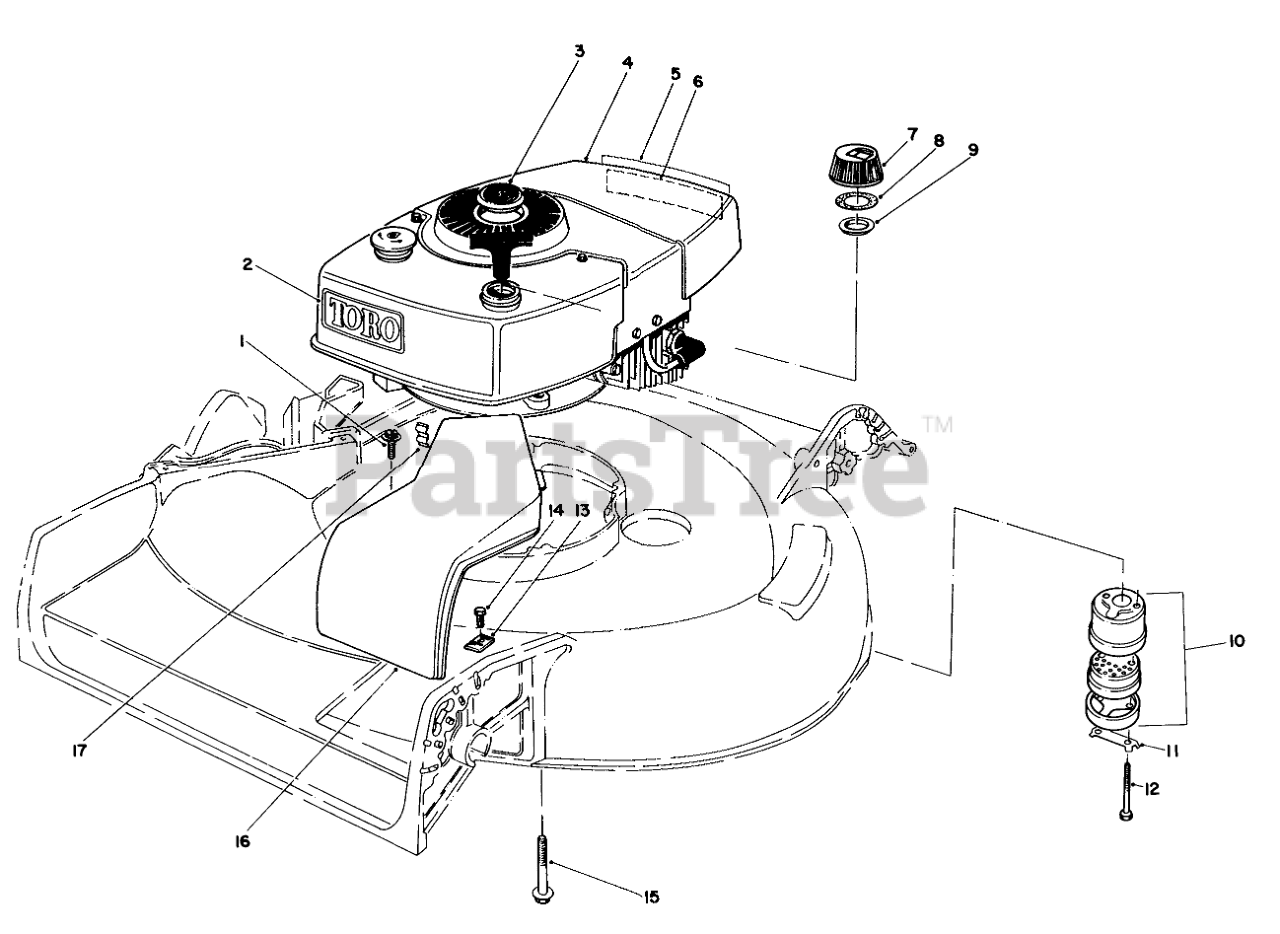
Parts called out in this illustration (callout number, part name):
1	SCREW
2	Decal Tow
3	Plug Button
4	Engine
5	Decal-Primer
6	Decal Maintenance
7	Fuel Cap (Incl. Ref. #8 & 9)
8	GASKET
9	GAS CAP BAFFLE
10	Muffler Assembly (Incl. #11 & 12)
11	CLIP - LOCKING
12	SCREW-HH
13	Cable Clamp
14	SCREW-HWHTF
15	3/8-16 X 2-3/4 CAPSCR
16	Cow-Belt
17	Clip Conduit
